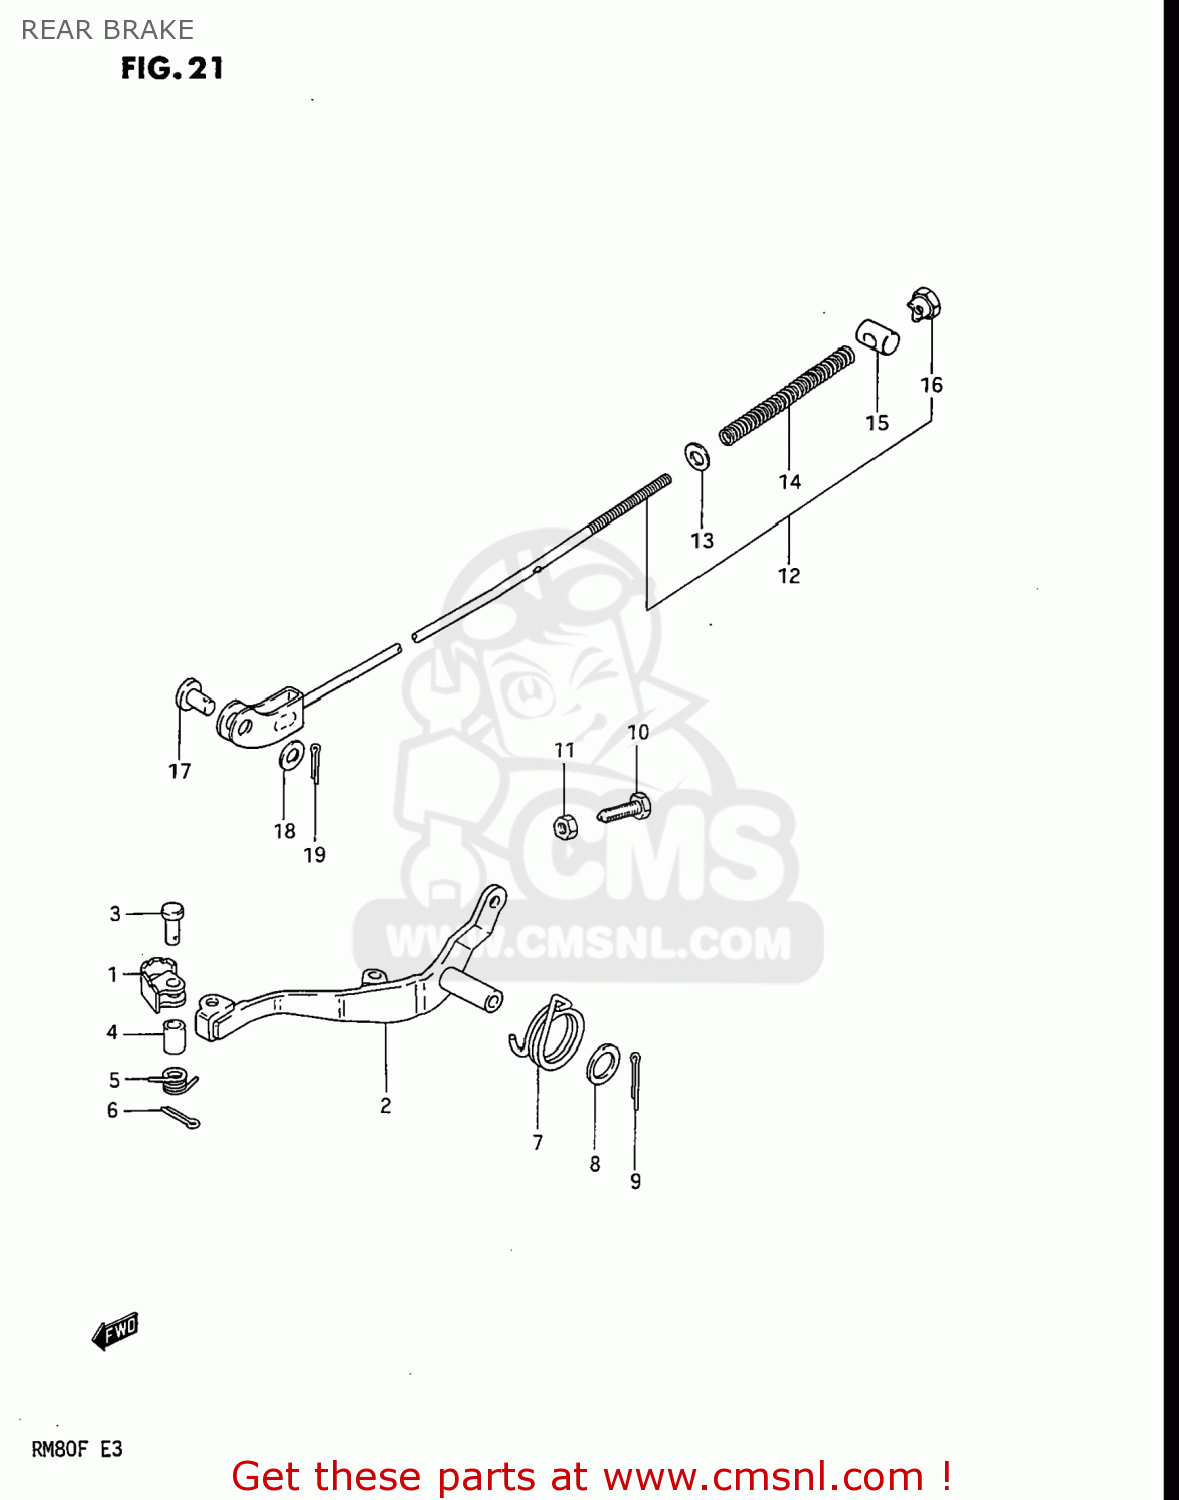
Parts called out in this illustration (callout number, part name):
1	PEDAL,BRAKE
2	ARM,BRAKE PEDAL
3	PIN
4	SPACER(9.2X9X6.5)
5	SPRING
6	PIN
7	SPRING
8	WASHER(15.5X26X2.3)
9	COTTER PIN
10	SCREW(6X23)
11	NUT
12	ROD ASSEMBLY,REAR BRAKE
13	WASHER
14	SPRING
15	PIN(11X18)
16	NUT (6MM)
17	PIN
18	WASHER
19	PIN 20X20
